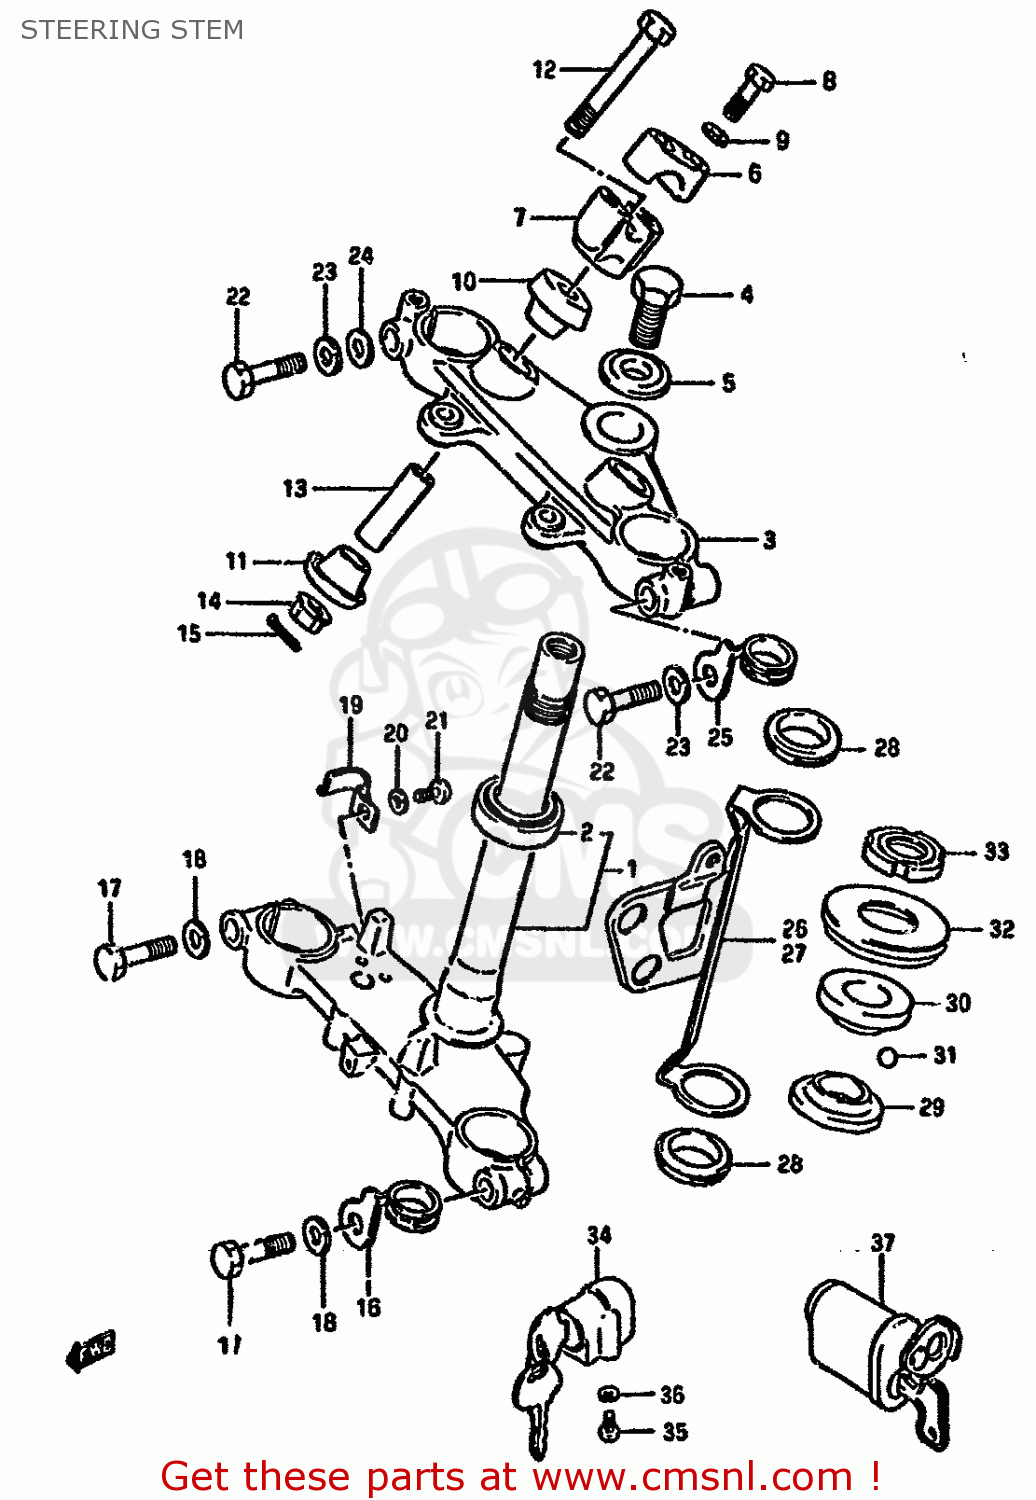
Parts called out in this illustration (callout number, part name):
1	STEM,STEERING
2	BEARING
3	HEAD,STEERING STEM
4	BOLT,STEERING STEM HEAD
5	WASHER
6	HOLDER,HANDLE UPR
7	HOLDER,HANDLEBAR LWR
8	BOLT
9	WASHER,LOCK,8.
10	RUBBER,HANDLE HOLDER
11	RUBBER,LWR
12	BOLT
13	SPACER
14	NUT
15	COTTER PIN
16	CLIP,LOWER
17	BOLT,INNER TUBE FITTING
18	WASHER,LOCK
19	CLIP
20	WASHER,LOCK
21	SCREW
22	BOLT,INNER TUBE FITTING
23	WASHER,LOCK
24	WASHER 10MM
25	CLIP,UPPER
26	BRACKET,HEADLAMP,R
27	BRACKET,HEADLAMP,L
28	CUSHION,HEADLAMP HSG BRACKET
29	RACE,STEERING INNER (SUJ)
30	RACE,STEERING,OUTER,UPPER
31	BALL
32	SEAL,STEERING UPR DUST
33	NUT,STEERING STEM
34	LOCK ASSY,STEERING
35	SCREW
36	LOCK WASHER
37	LOCK ASSY,STEERING(NEIMAN)
